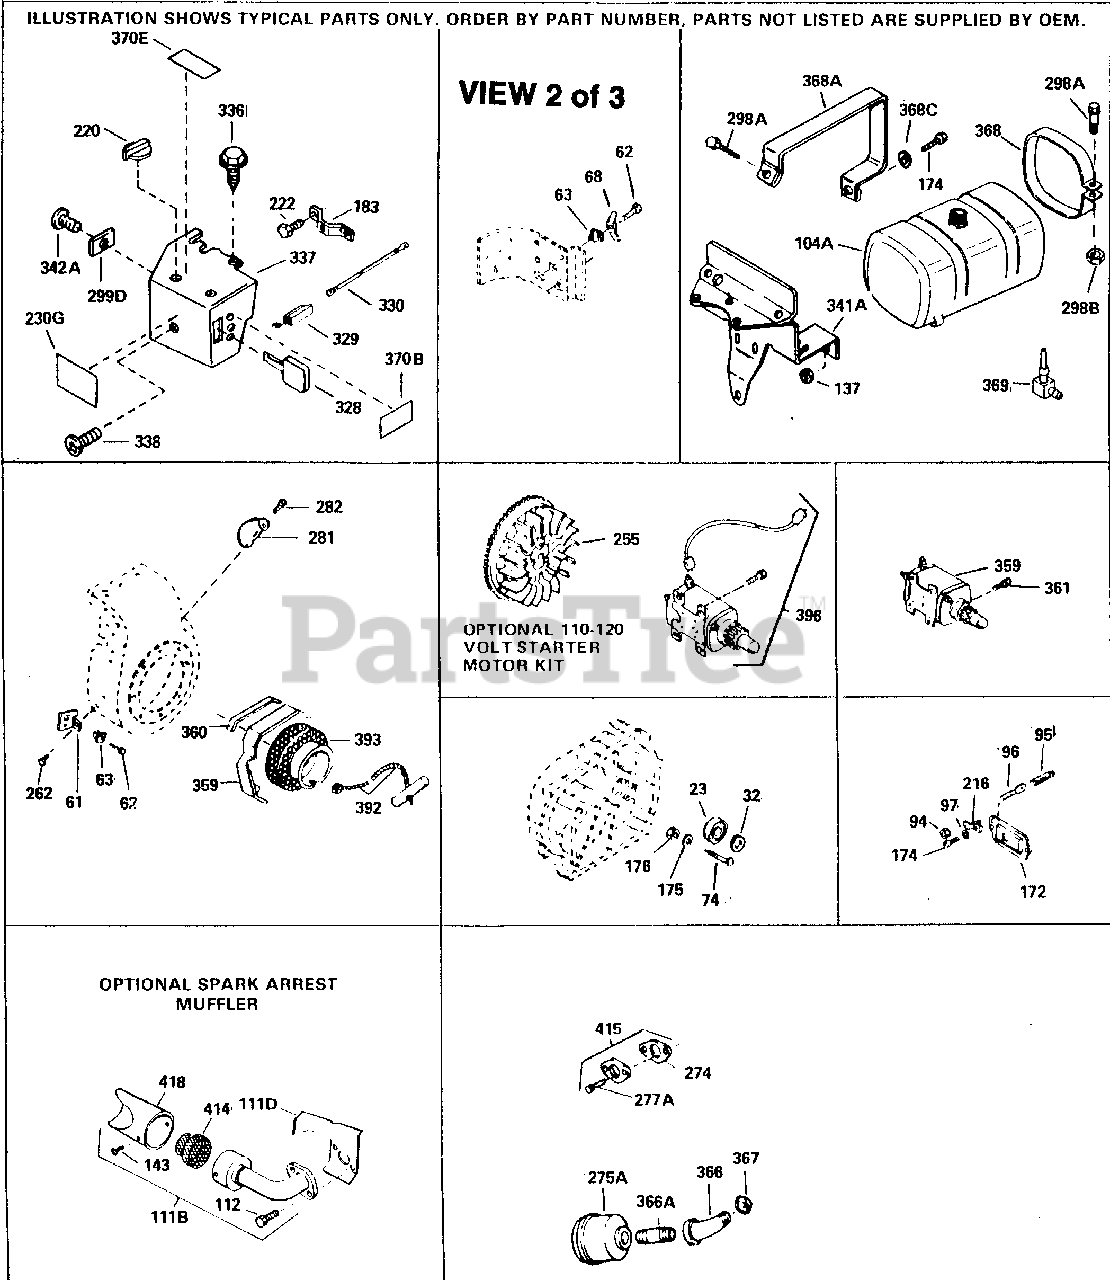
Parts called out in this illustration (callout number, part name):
16A	Governor Bracket
42	Ring Set (Std.)
42	Ring Set (.010" OS)
42	Ring Set (.020" OS)
172	Valve Cover
174	Screw, 10-24 x 1/2"
178	Nut & Lock Washer 1/4-28
200	Control Bracket
238	Screw, 10-32 x 1-1/8"
239	Air Cleaner Gasket
262	Screw, T-40, 5/16-24 x 21/32"
265	Cylinder Head Cover
272	Screw, 5/16-18 x 3/4"
273	Carburetor Flange
277A	Screw, 5/16-18 x 3/4"
291	Fuel Line
307	"O" Ring
310	Dipstick
345	Heat Baffle
366	Muffler Elbow
366A	Muffler Nipple
370B	Decal - Important Lubrication - SAE 3
450	Pre-Cleaner Kit
451	Pre-Cleaner Bag Spring
452	Air Filter
